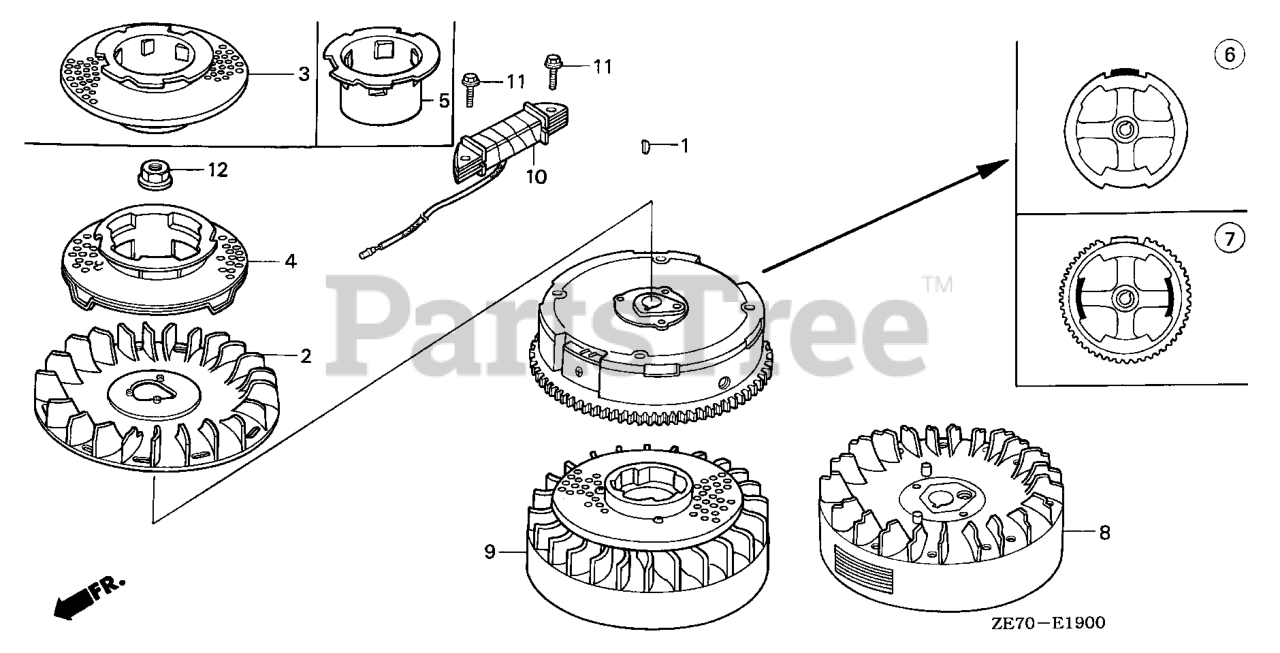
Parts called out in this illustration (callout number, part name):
1	KEY, SPECIAL WOODRUFF (25X18)
9	FLYWHEEL ASSY.
12	NUT, SPECIAL (14MM)
